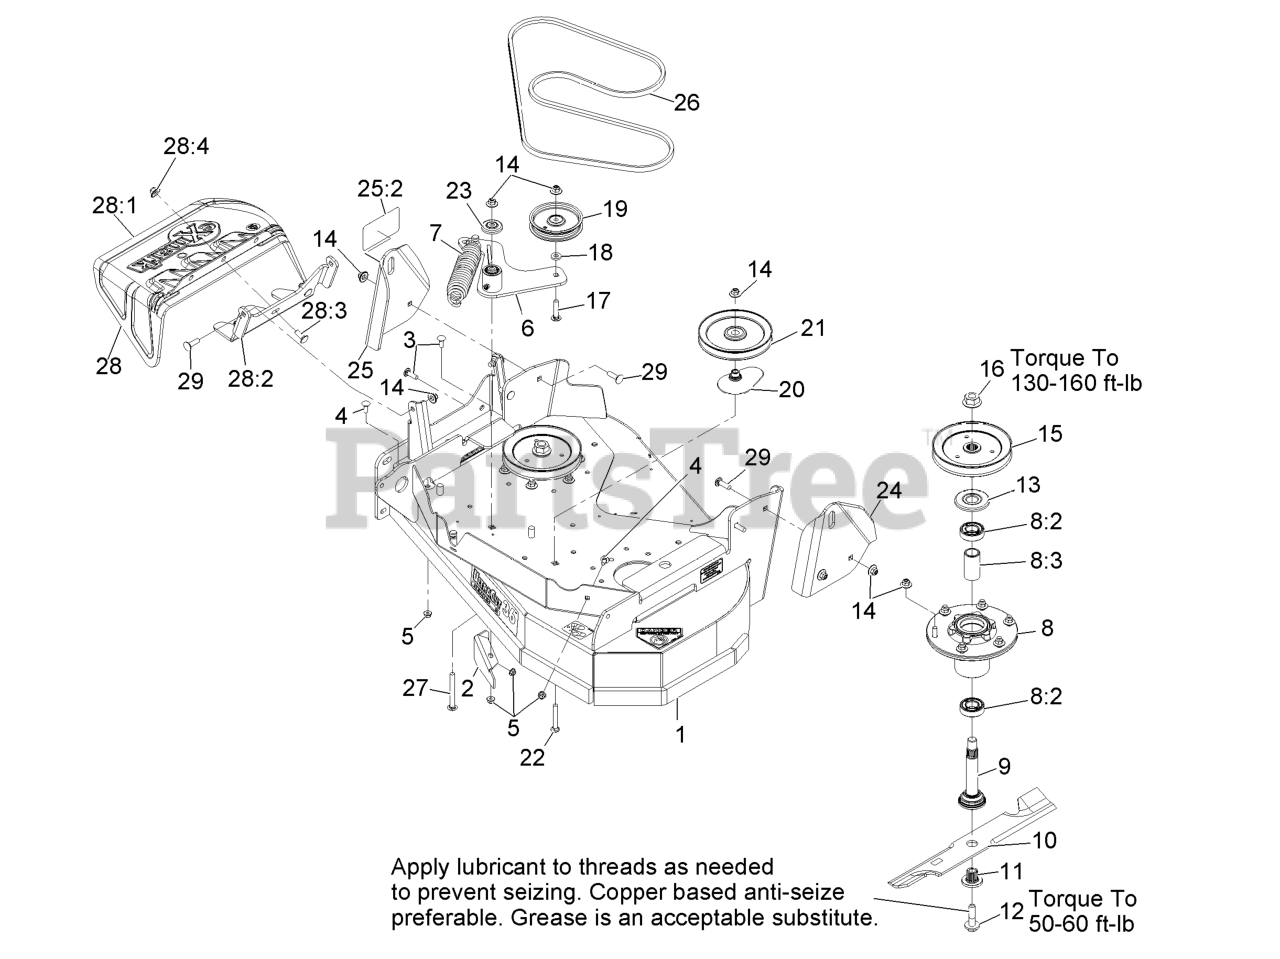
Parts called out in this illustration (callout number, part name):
1	DECK ASM - 36
2	BAFFLE-DOGLEG
3	SCREW-CARR
4	SCREW-CARR
5	NUT-HF, NI
6	IDLER ARM ASM -
8	ASM-CUTTER HSG WITH BEARINGS
8:2	BEARING-BALL
8:3	SPACER-BEARING
9	ASM-SPINDLE AND SEAL
11	BUSHING,SPLINED
12	SCREW,SEMS 1/2-20 X 2.19
13	GUARD,BEARING TOP .989
14	Nut-Nyloc 3/8-16 Flg
15	SHEAVE,BLADE DRIVE 6.50
16	NUT-FLANGE
17	SCREW-CARR
19	PULLEY-IDLER
20	SPACER-PULLEY
21	PULLEY-IDLER
22	SCREW-CARR
23	GUARD-TOP
24	PUSH-TOWER,LH 36
25	PUSH TOWER-RH 36, W/DECAL
25:2	DECAL-WARNING, DISCHARGE
26	BELT-V
27	BOLT-SHOULDER, CARRIAGE 3/8-16 X 3 1/2
28	CHUTE - DISCHARGE ASM
28:1	CHUTE,DISCHARGE
28:2	BRACKET-CHUTE, DISCHARGE
28:3	SCREW-CARR
28:4	Nut-Nyloc 3/8-16 Flg
29	Bolt-Carriage 3/8-16 X 1 1/4
